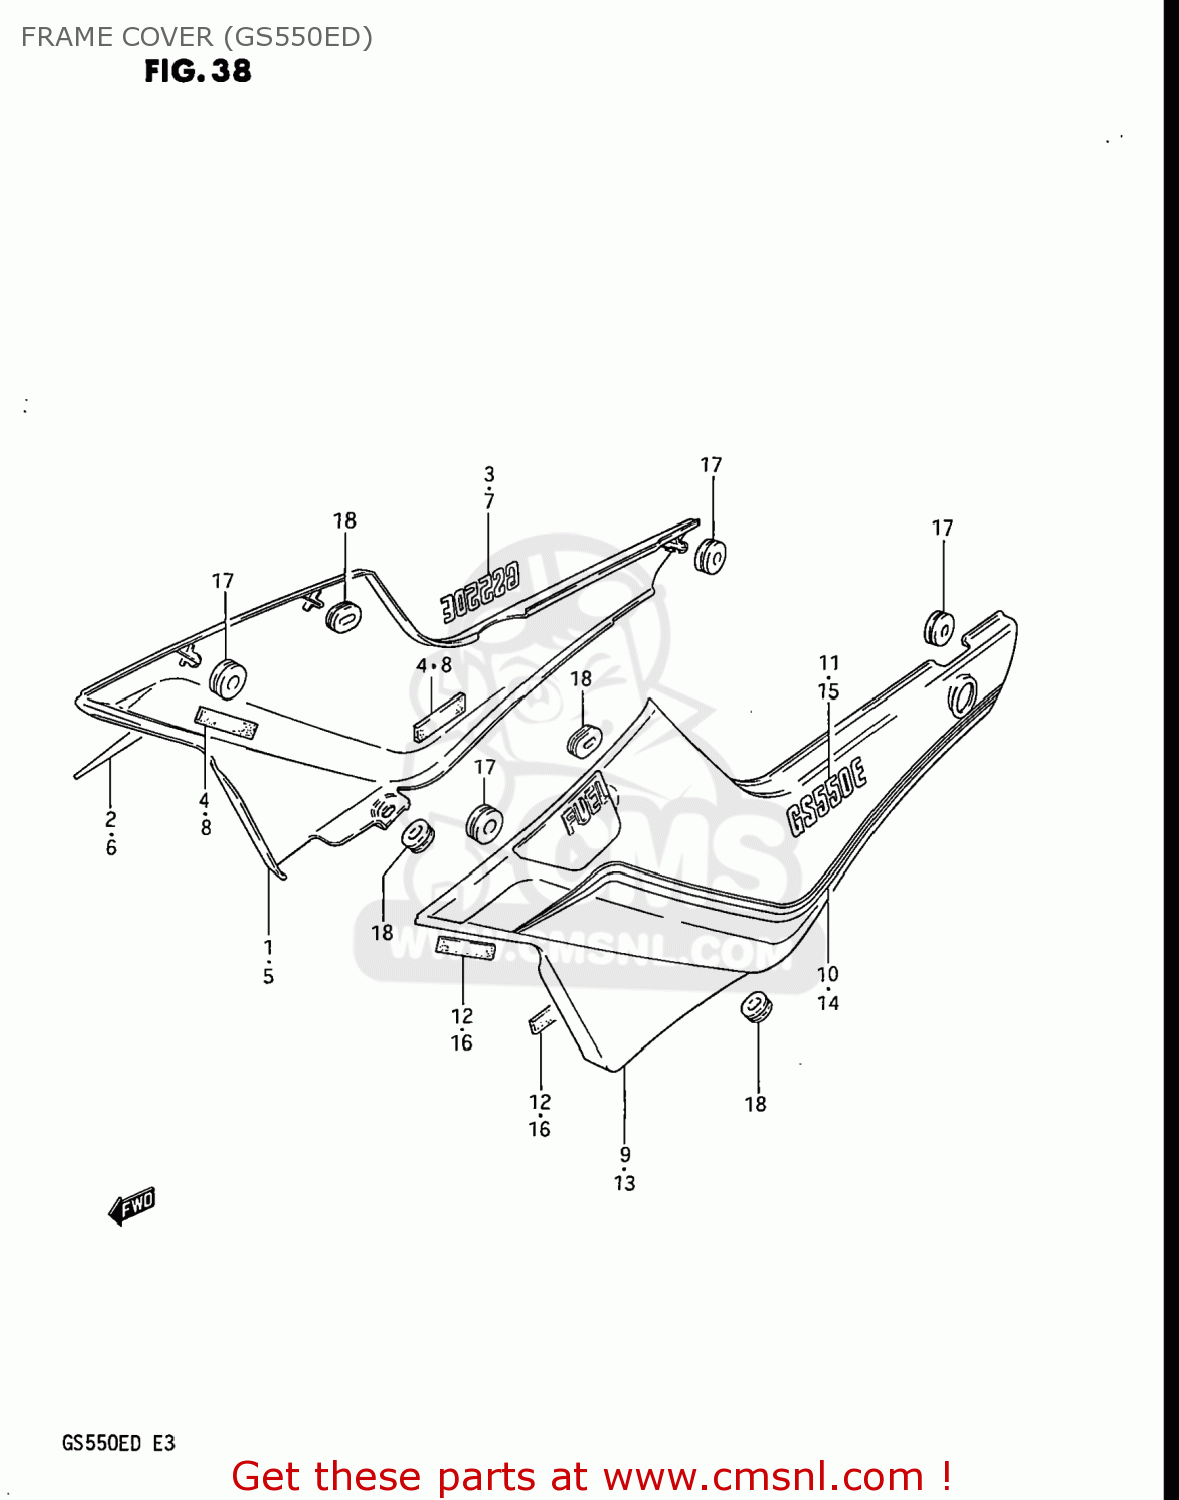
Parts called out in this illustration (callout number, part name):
1	COVER ASSEMBLY,FRAME,RIGHT
2	TAPE SET,FRAME COVER
3	EMBLEM
4	RUBBER,FRAME COVER
5	COVER ASSEMBLY,FRAME,RIGHT
6	TAPE SET,FRAME COVER
7	EMBLEM
8	RUBBER,FRAME COVER
9	COVER ASSEMBLY,FRAME,LEFT
10	TAPE SET,FRAME COVER
11	EMBLEM
12	RUBBER,FRAME COVER
13	COVER ASSEMBLY,FRAME,LEFT
14	TAPE SET,FRAME COVER
15	EMBLEM
16	RUBBER,FRAME COVER
17	CUSHION
18	CUSHION
